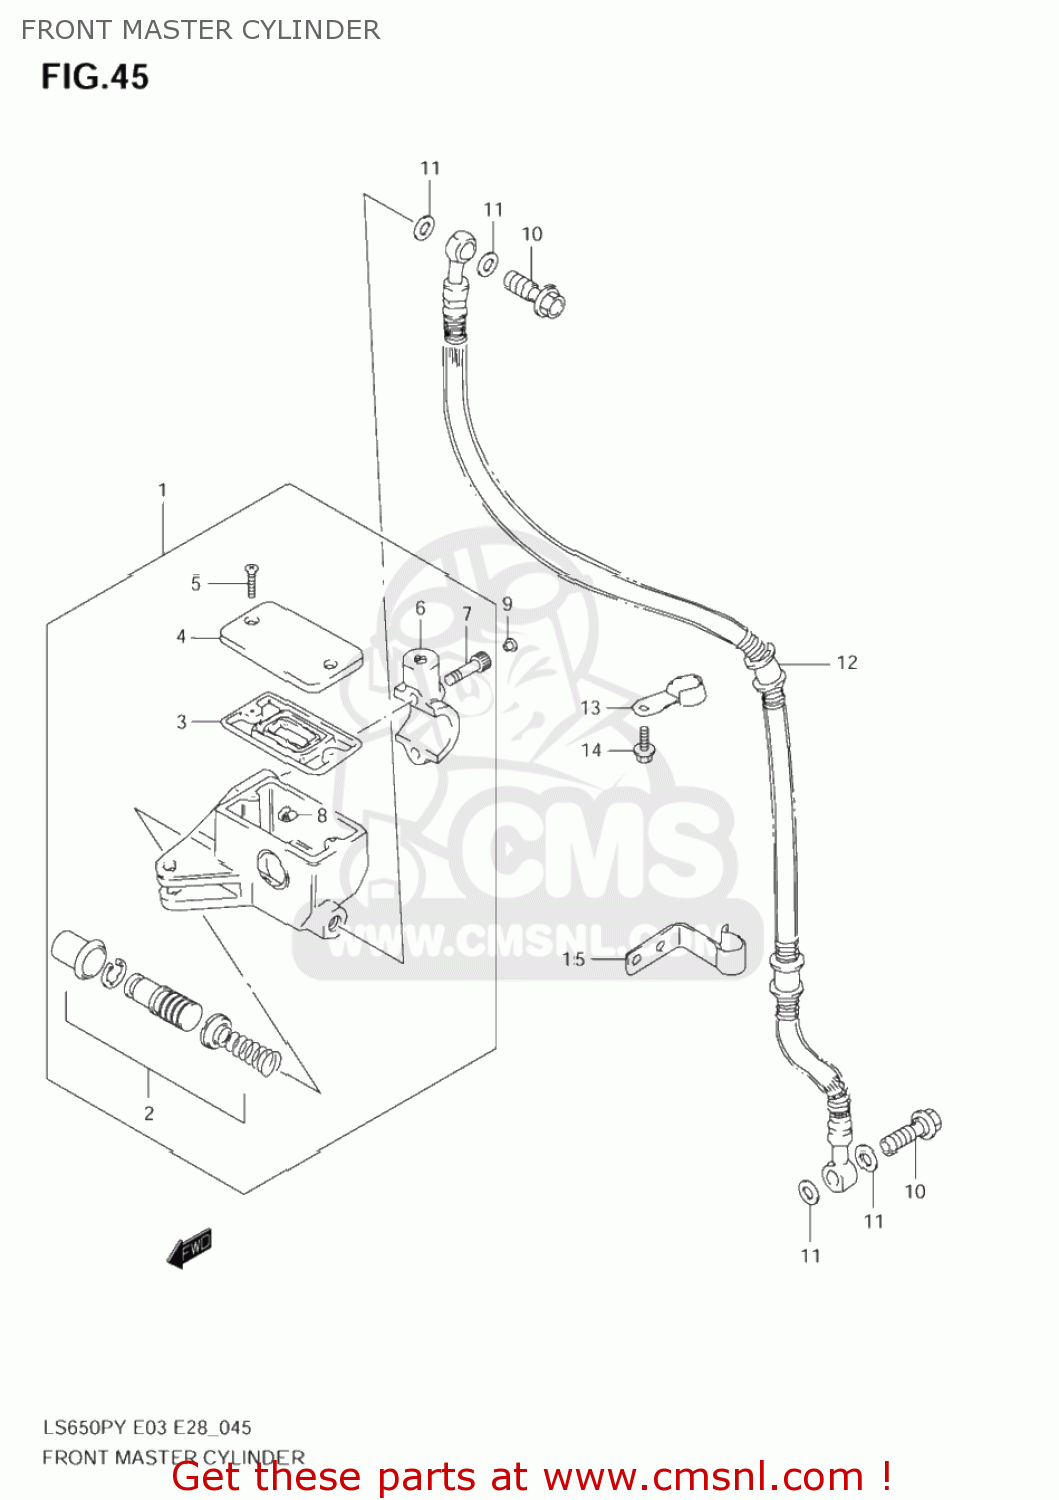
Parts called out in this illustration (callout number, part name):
1	CYLINDER ASSY,FR MASTER
2	PISTON/CUP SET
3	4
4	CAP
5	SCREW
6	HOLDER
7	BOLT
8	PROTECTOR
9	CAP(OD:10)
10	BOLT UNION
11	WASHER(10X15X1.5)
12	HOSE,FR BRAKE
13	GUIDE,BRAKE HOSE NO.1
14	BOLT
15	GUIDE,BRAKE HOSE NO.2
